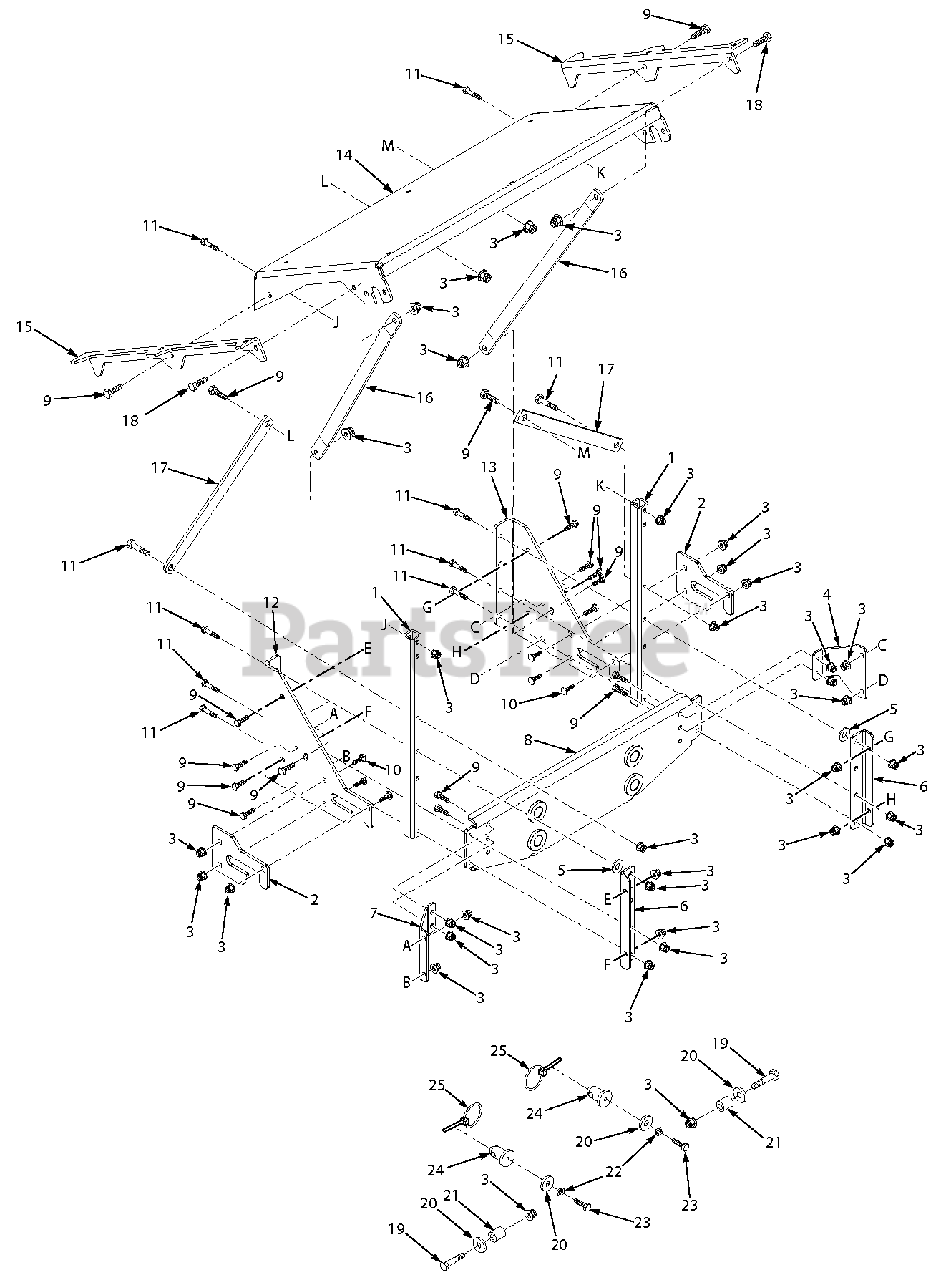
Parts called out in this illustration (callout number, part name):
1	Tube, Upright
2	Wear Plate, GC
3	Nut, Elastic Flange 3/8-16
4	Angle Brace, LH GC
5	Flatwasher, .469 X 1.75 X .25
6	Mounting Bracket, GC Tube
7	Angle Brace, RH GC
8	Mounting Bracket Weldment
9	Bolt, Hex Head 3/8-16 x 1"
10	Bolt, Carriage 3/8-16 x 1"
11	Bolt, Hex Head 3/8-16 x 2-1/2"
12	RH Mounting Bracket, GC
13	LH Mounting Bracket, GC
14	Support Frame, Hopper
15	Bracket, Hopper Support
16	Brace, Stiffener Long
17	Brace, Engine Mount
18	Bolt, Hex Head 3/8-16 x 1"
19	Bolt, Hex Head 3/8-16 x 2-1/4"
20	Flatwasher, 3/8-.406 x 1.50 x 7 Ga.
21	Spacer
22	Lockwasher, 3/8"
23	Bolt, Hex Head 3/8-16 x 1-1/4"
24	Pin, GC Locator
25	Quick Pin
